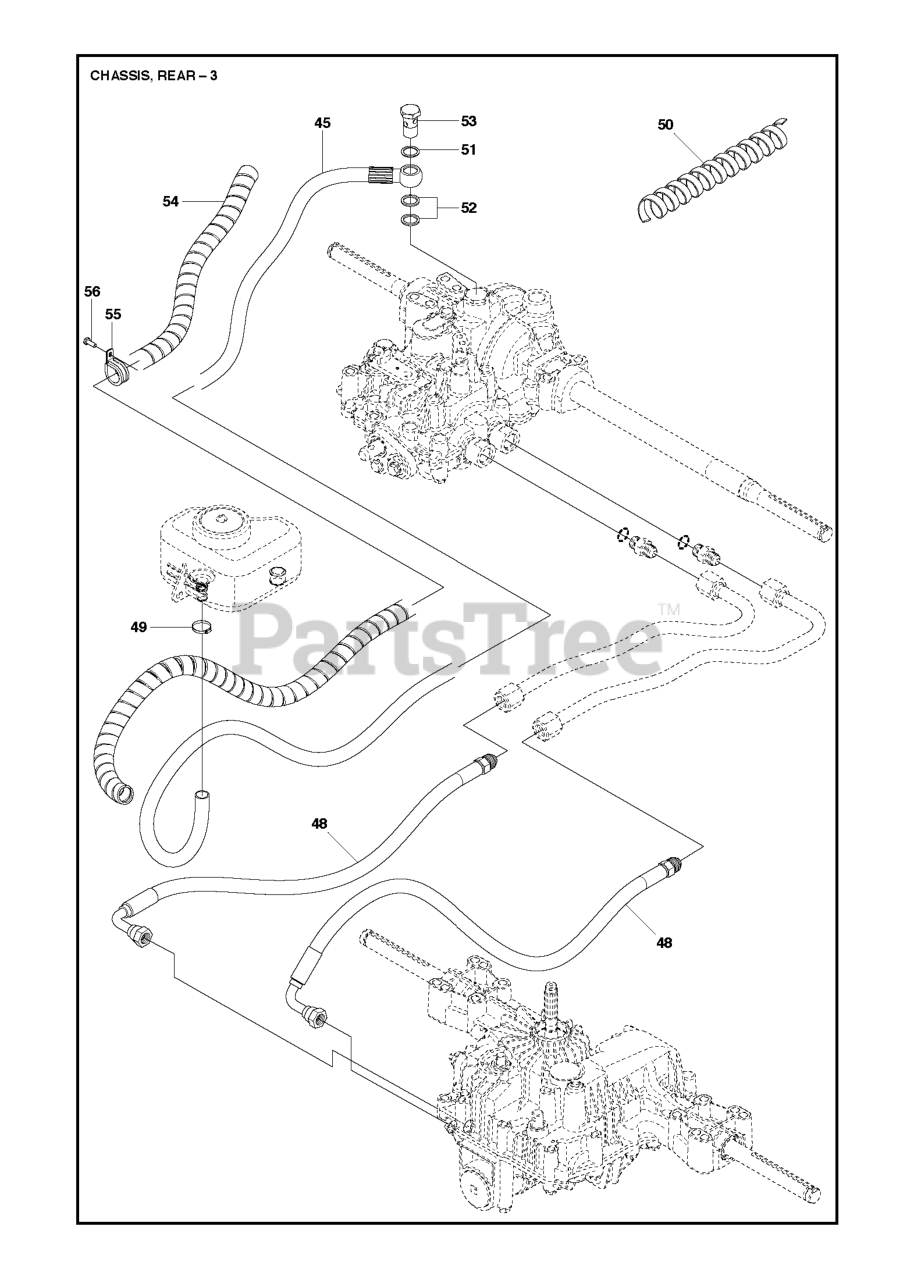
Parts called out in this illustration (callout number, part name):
2	VALVE STEM LT
3	TIRE HEAVY DUTY
4	TUBE.5.3/4.5/6
5	RIM ASM 6" FRONT SILVER
6	FITTING LT
7	BEARING T
8	RIM ASM 8" REAR SILVER
9	TIRE.TS.20X10-8
10	TUBE
11	CAP, AXLE BLK
